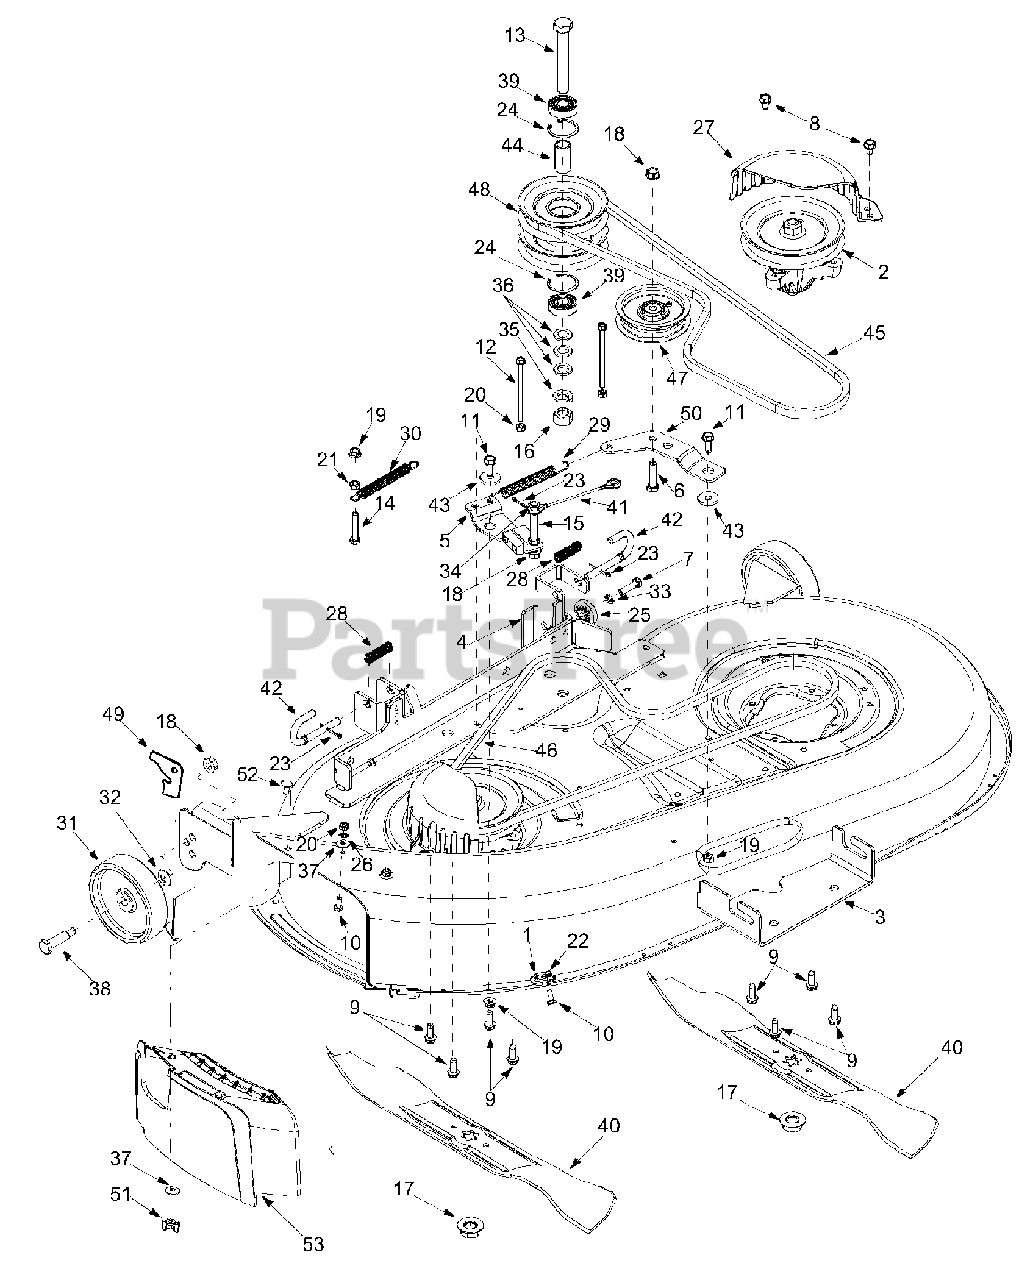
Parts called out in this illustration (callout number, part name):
1	Bracket: Retainer Hook
2	Spindle Assembly: Pulley
5	Brake Assembly: deck
6	Hex Screw 3/8-16 x 1.5
7	Hex Screw 5/16-18 x 1.25
8	TT Screw 5/16-18 x 0.625
9	TT Screw 5/16-18 x 0.875
10	Hex Screw 1/4-20 x 0.620
11	Hex Washer Head Screw
12	TT Screw 1/4-20 x 4.0
13	Hex Screw 5/8-18 x 4.25
14	Hex Screw 5/16-18 x 1.75
16	Hex Nut 5/8-18
17	Flange Nut 5/8-18
18	Flange Lock Nut
19	Flange Lock Nut
20	Hex Nut 1/4-20
21	Hex Nut 5/16-18
22	Lock Nut 1/4-20
23	Cotter Pin
24	Snap Ring
25	Gear: Deck Adjustment
26	Push Nut
27	Belt Cover
28	Compression Spring
29	Extension Spring
30	Extension Spring
31	Deck Wheel
32	Bell Washer
33	Lock Washer
34	Flat Washer
35	Lock Washer
36	Flat Washer
37	Bell Washer
38	Sholder Spacer
39	Bearing
40	Blade
41	Brake Cable
42	Deck Release Rod
43	Shoulder Spacer
44	Spacer
45	V-Belt
46	V-Belt
47	Idler Pulley
48	Double Pulley
49	Chute Stop
51	Wing Nut
52	Carriage Screw
53	Mulch Plug
